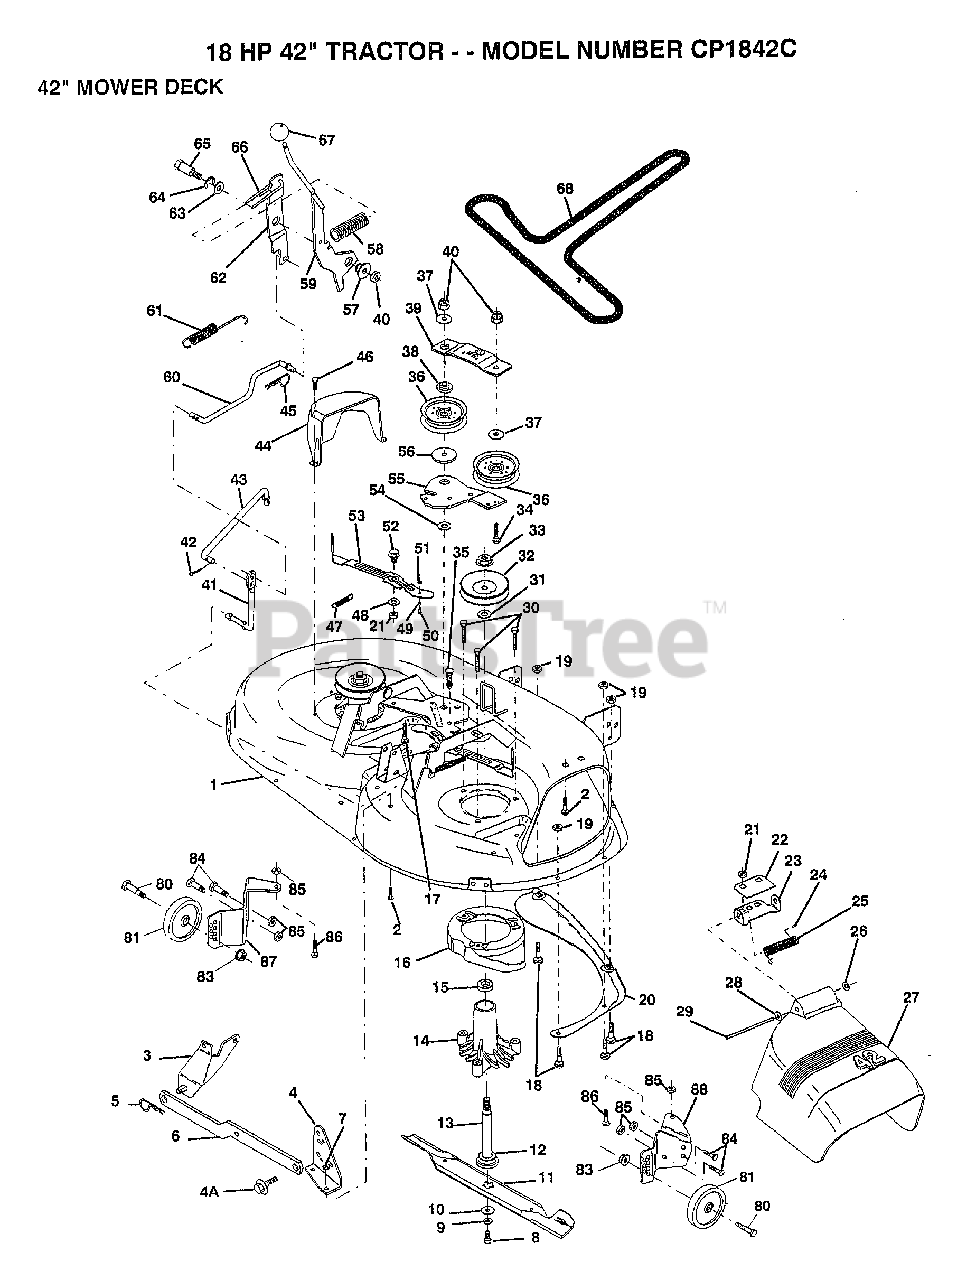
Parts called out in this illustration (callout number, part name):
2	BOLT
3	BRKT ASM SWAY BAR
4	BRKT DECK SW BAR
4A	BOLT SHD 5/16-18
7	NUT
8	BLADE BOLT
10	WASHER BLADE
11	"BLADE.42"" HIPERF"
12	BEARING.BALL
14	HSG ASM MANDREL
15	BEARING
17	BOLT CARRIAGE
18	BOLT
19	NUT
22	STIFFENER BRKT
23	DEFLECTOR BRKT
24	CAP-SLEEVE LT
25	SPRING TORSION
26	NUT PUSH M
27	DEFLECTOR.SHIELD
28	WASHER
29	HINGE ROD
31	WASHER
34	BOLT
35	XMAS TREE FASTNER
36	FLAT IDLER PULLEY
37	WASHER GT
38	RETAINER SPACER
39	IDLER ARM STIFF
41	PIVOT ROD
43	CLUTCH ROD SECOND
45	RETAINER M
46	SCREW.1/4-20X5/8
47	SPRING EXTENSION
48	HARD SMALL WASHER
50	SHOULDER BOLT
51	LOCKNUT
53	BRAKE PAD ARM ASM
54	HARDENED WASHER
55	IDLER ARM
56	SPACER RETAINER
57	BUSHING
59	LEVER.ASM.CLUTCH
60	"ROD, CLUTCH PRIM"
61	RETURN SPRING
62	CLUTCH ARM SECOND
63	WASHER
64	RING
65	SHOULDER BOLT
66	SPRING KEEPER
68	BELT-V.92.4.MWR
80	BOLT M
81	WHEEL.GAGE.BLK.PL
83	NUT
84	BOLT
